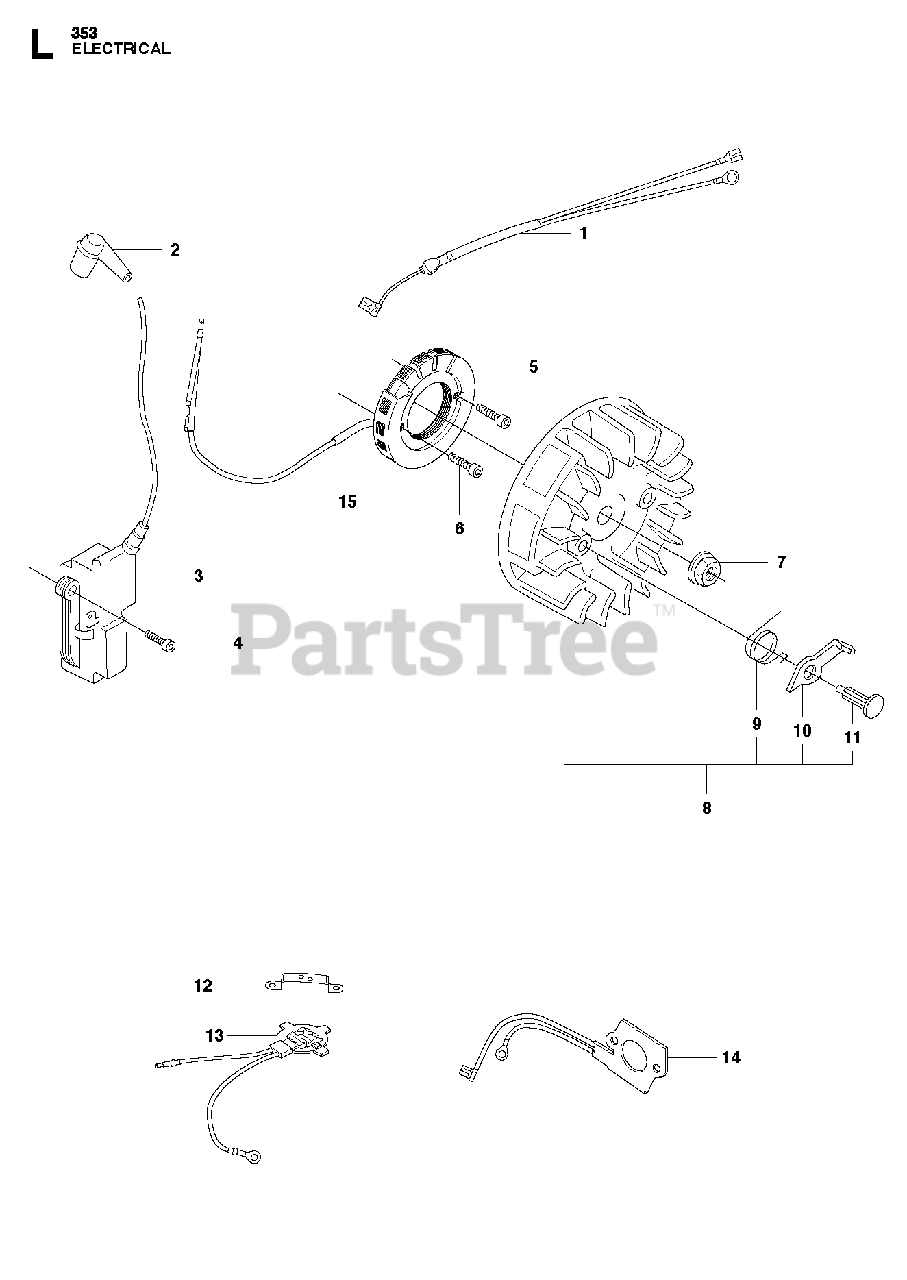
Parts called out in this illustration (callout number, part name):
1	WIRING ASSY
1	WIRING ASSEMBLY
2	SPARK PLUG CONN. KIT
3	IGNITION MODULE
5	GENERATOR
5	GENERATOR STATOR
7	NUT W/ WASHER
8	FLYWHEEL (G)
8	RP FLYWHEEL
9	%SPRING, STARTER CATCH
10	PAWL
11	RIVET
12	RETAINER
13	THERMOSTAT ASSY
14	Heating Plate
15	Cable Cover
